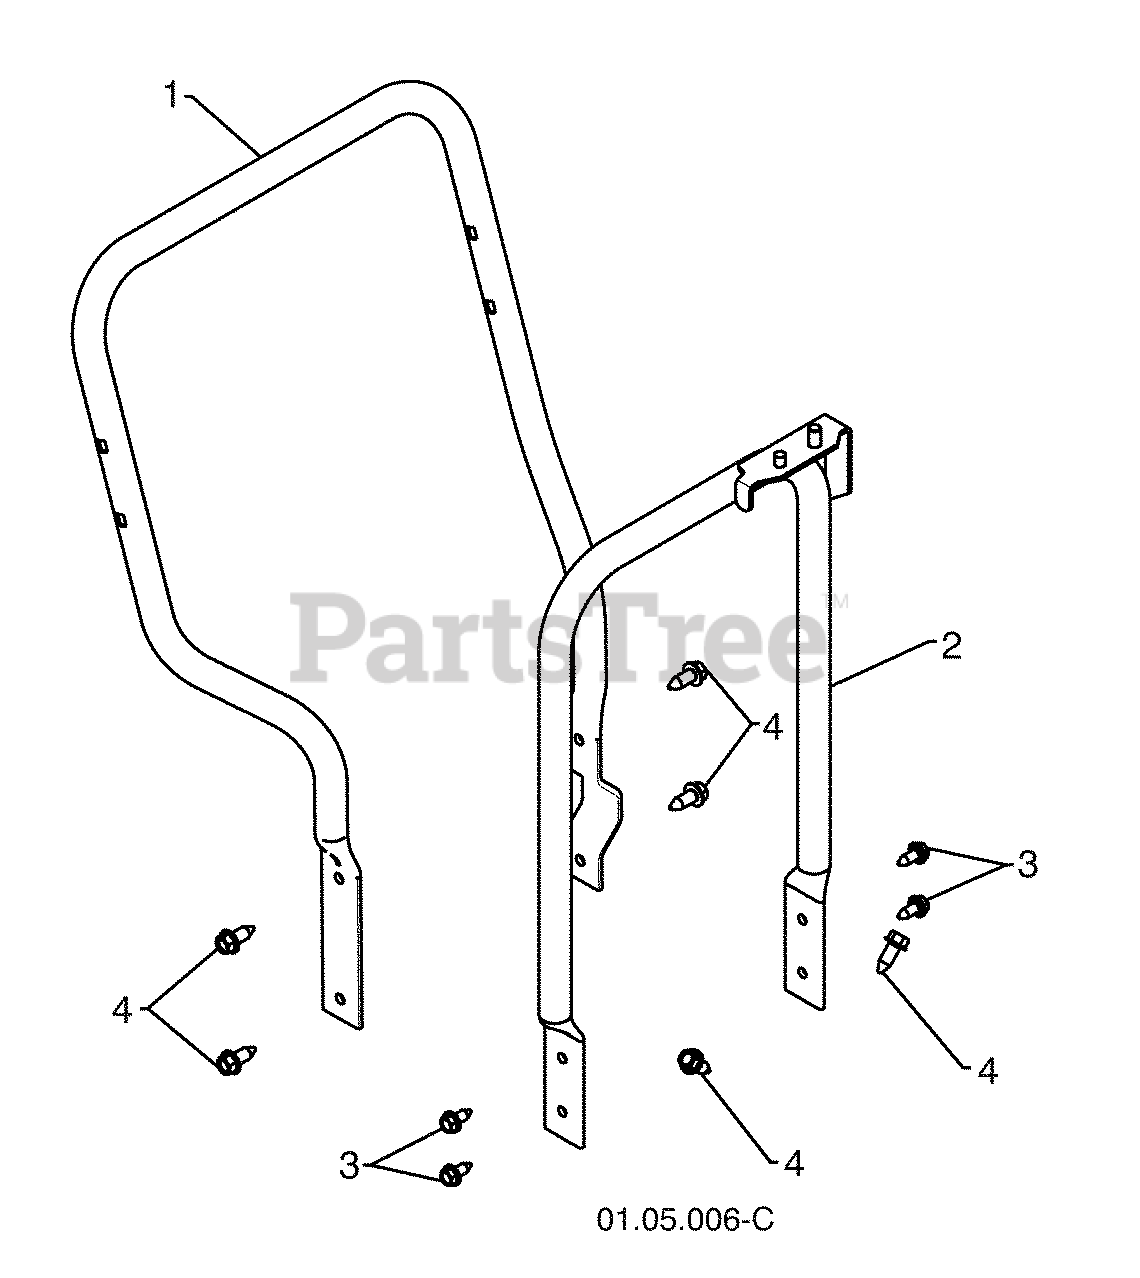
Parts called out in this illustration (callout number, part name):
1	LOWER TUBE GRAY
2	PIVOT SUPPORT
3	BOLT 5/16-18 X .750
4	SCREW 3/8-16 X 1.00
